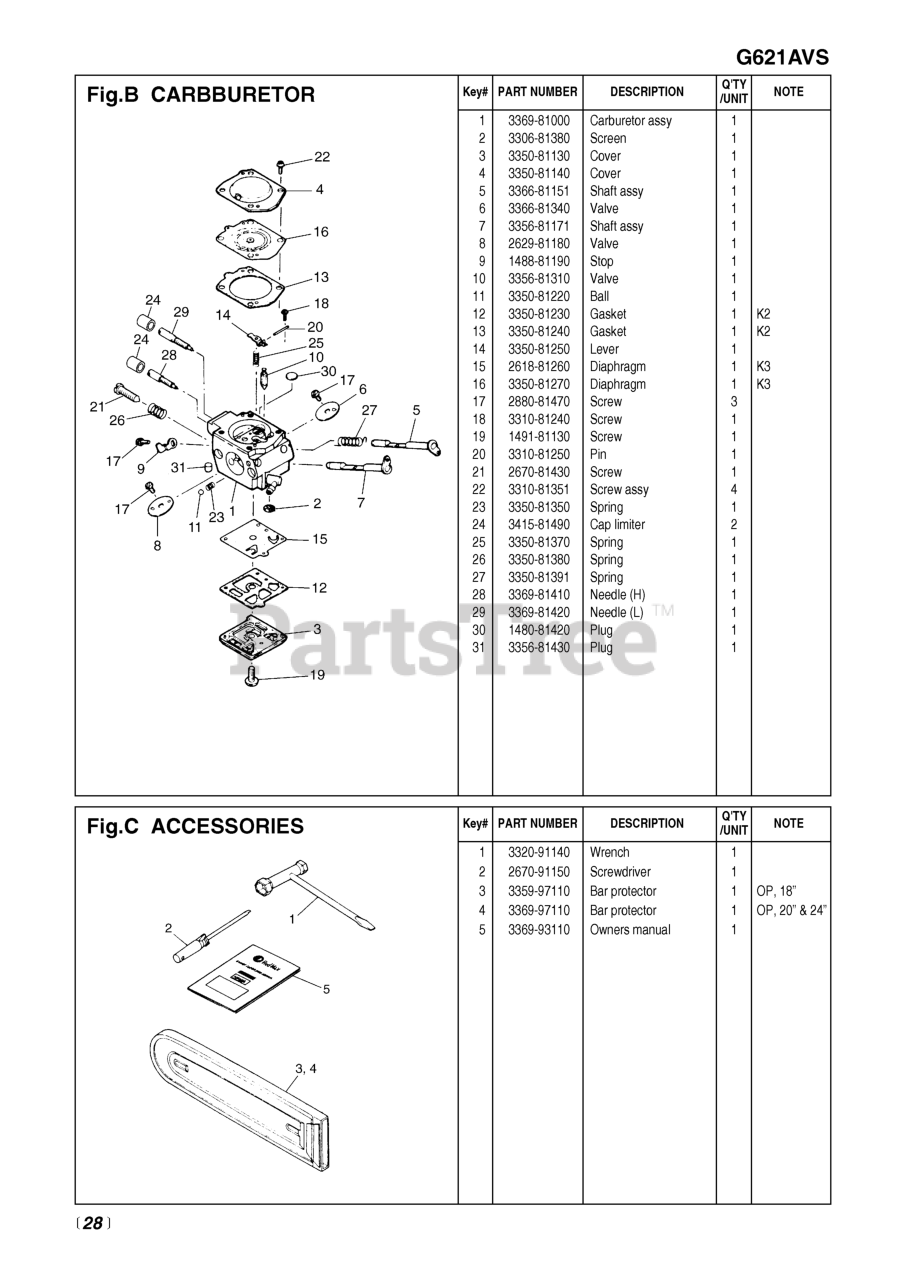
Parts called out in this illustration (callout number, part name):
1	CARBURETOR (HDA-212-1)
4	DIAPHRAGM
6	VALVE, THROTTLE
7	CHOKE SHAFT A
10	VALVE, INLET
11	BALL, FRICTION
12	KIT ONLY
13	KIT ONLY
14	KIT ONLY
15	DIAPHRAGM
16	KIT ONLY
17	SCREW (RPLS 3310-81360)
20	PIN, METERING LEVER
22	SCREW ASSEMBLY
23	SPRING
24	CAP, LIMITER
25	KIT ONLY
26	SPRING, IDLE
27	SPRING, RETURN
28	NEEDLE (H)
29	NEEDLE (L)
30	PLUG, WELSH
31	PLUG, FRICTION
A1	WRENCH, PLUG
A2	SCREWDRIVER
A4	PROTECTOR (USE 3665-97110)
